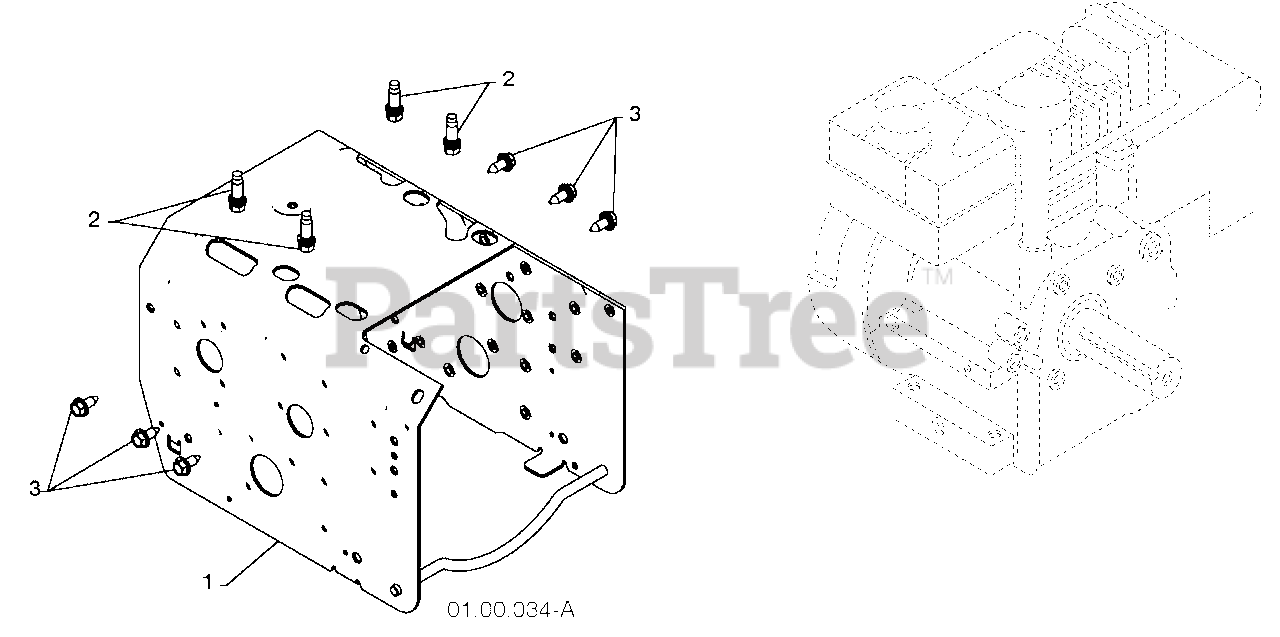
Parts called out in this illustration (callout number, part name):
1	FRAME
2	BOLT 3/8-16
3	SCREW 5/16-18 X .750
